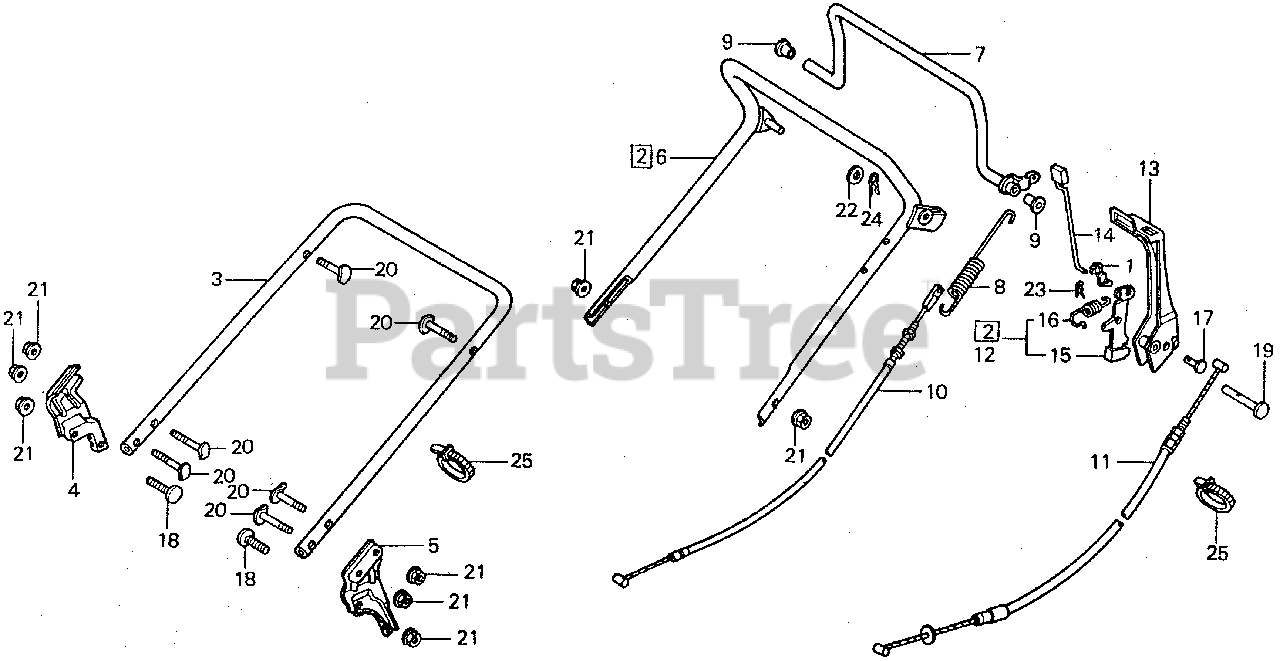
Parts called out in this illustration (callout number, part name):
1	JOINT, ROD
2	HANDLE SET (UPPER)
3	PIPE, HANDLE (LOWER)
4	STAY, R. HANDLE
5	STAY, L. HANDLE
6	HANDLE SET (UPPER)
7	LEVER, CLUTCH
8	SPRING, CLUTCH (NOT AVAILABLE)
9	BUSH, CLUTCH LEVER
10	CABLE, CLUTCH
11	CABLE, ROTO-STOP CLUTCH
12	LEVER SET, LOCK (NOT AVAILABLE)
13	LEVER, ROTO-STOP (NOT AVAILABLE)
14	ROD, RATCHET PUSH (NOT AVAILABLE)
15	LEVER, LOCK
15	LEVER, LOCK (NOT AVAILABLE)
16	SPRING, RATCHET RETURN
17	PIN, SEAT HINGE
18	BOLT, SPECIAL (8X15)
19	PIN, CLUTCH LEVER (NOT AVAILABLE)
20	BOLT, HANDLE HOLDER (NOT AVAILABLE)
21	NUT, FLANGE (8MM)
22	WASHER, PLAIN (8MM)
23	PIN, LOCK (6MM)
24	PIN, LOCK (8MM)
25	BAND B2, WIRE
